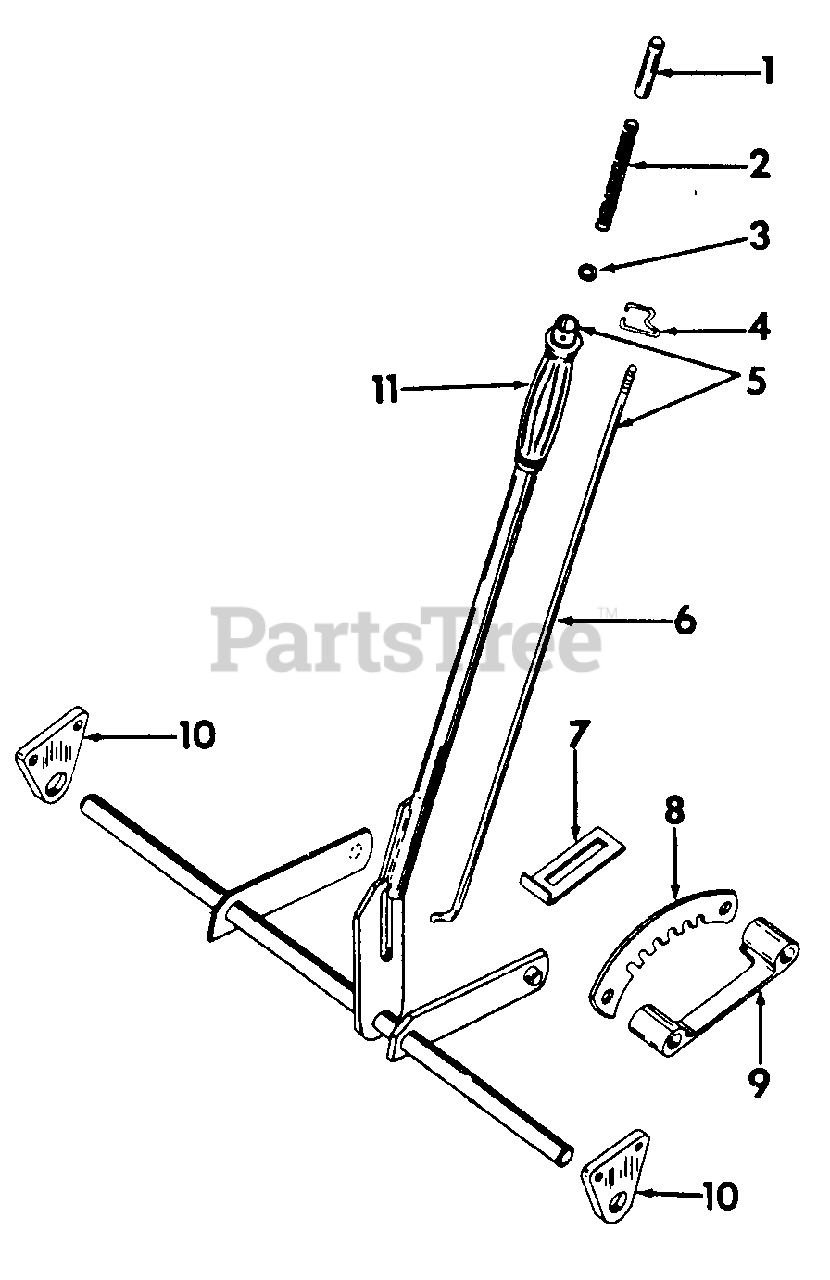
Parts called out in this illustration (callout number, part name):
1	Pin, Handle Release Rod
2	Spring, Release Rod Return
3	Washer, Release Rod Return Spring
4	Lock, Release Rod
5	Handle Assy, Lift
6	Rod, Handle Release
7	Stop, Lift Arm
8	Ratchet, Lift
9	Spacer Assy, Lift Ratchet
10	Bracket, Lift Handle Shaft
11	Grip, Lift Handle
